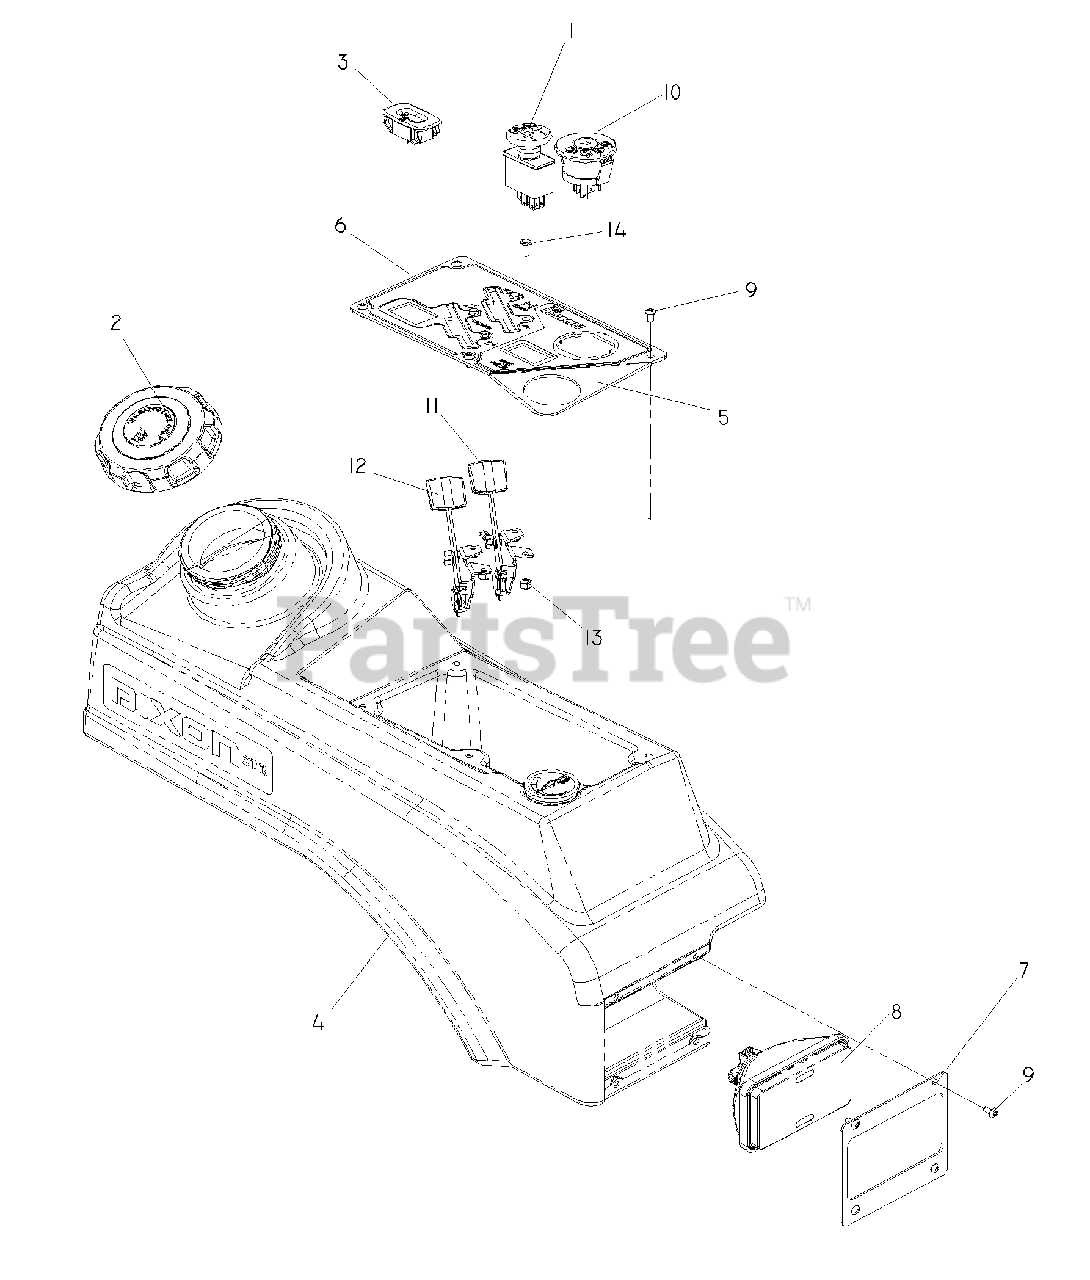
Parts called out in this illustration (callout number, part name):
1	SWITCH, BLADE
2	FUEL CAP ANTI-SPLASH
3	HOUR METER
4	TANK, FUEL, RT
5	CONTROL PANEL
6	DECAL, CONTROL
7	PLATE LIGHT
9	SCR #10-24 X 3/8 SKT HD BLK OX
10	IGNITION SWITCH
11	CABLE THROTTLE
12	CABLE THROTTLE
13	NUT 10-24 NYLOC
14	HCS #10-24 X 1/2
